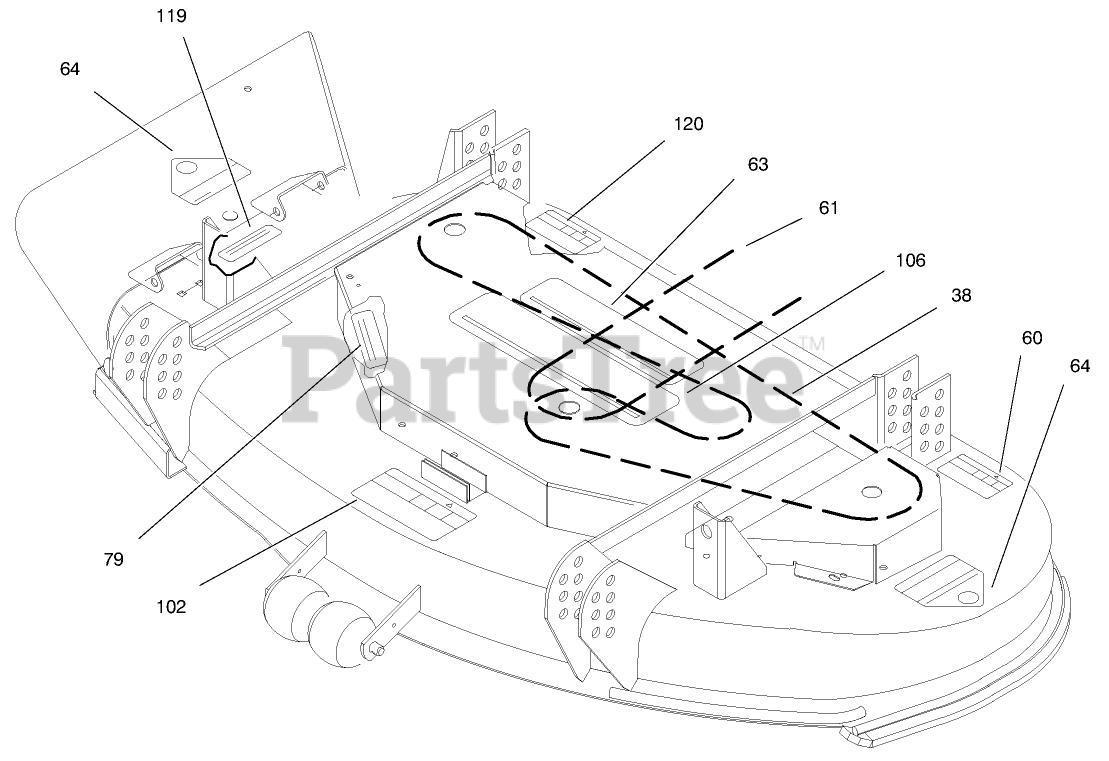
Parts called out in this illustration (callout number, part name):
38	V-BELT
60	DECAL-TORQUE, BLADE BOLT
61	V-BELT, DRIVE
63	DECAL-PROLINE
64	DECAL-DANGER
79	DECAL-DANGER
102	DECAL-DANGER
106	Decal-112 Cm
119	DECAL-WARNING, DEFLECTOR
120	DECAL-EUROPE
